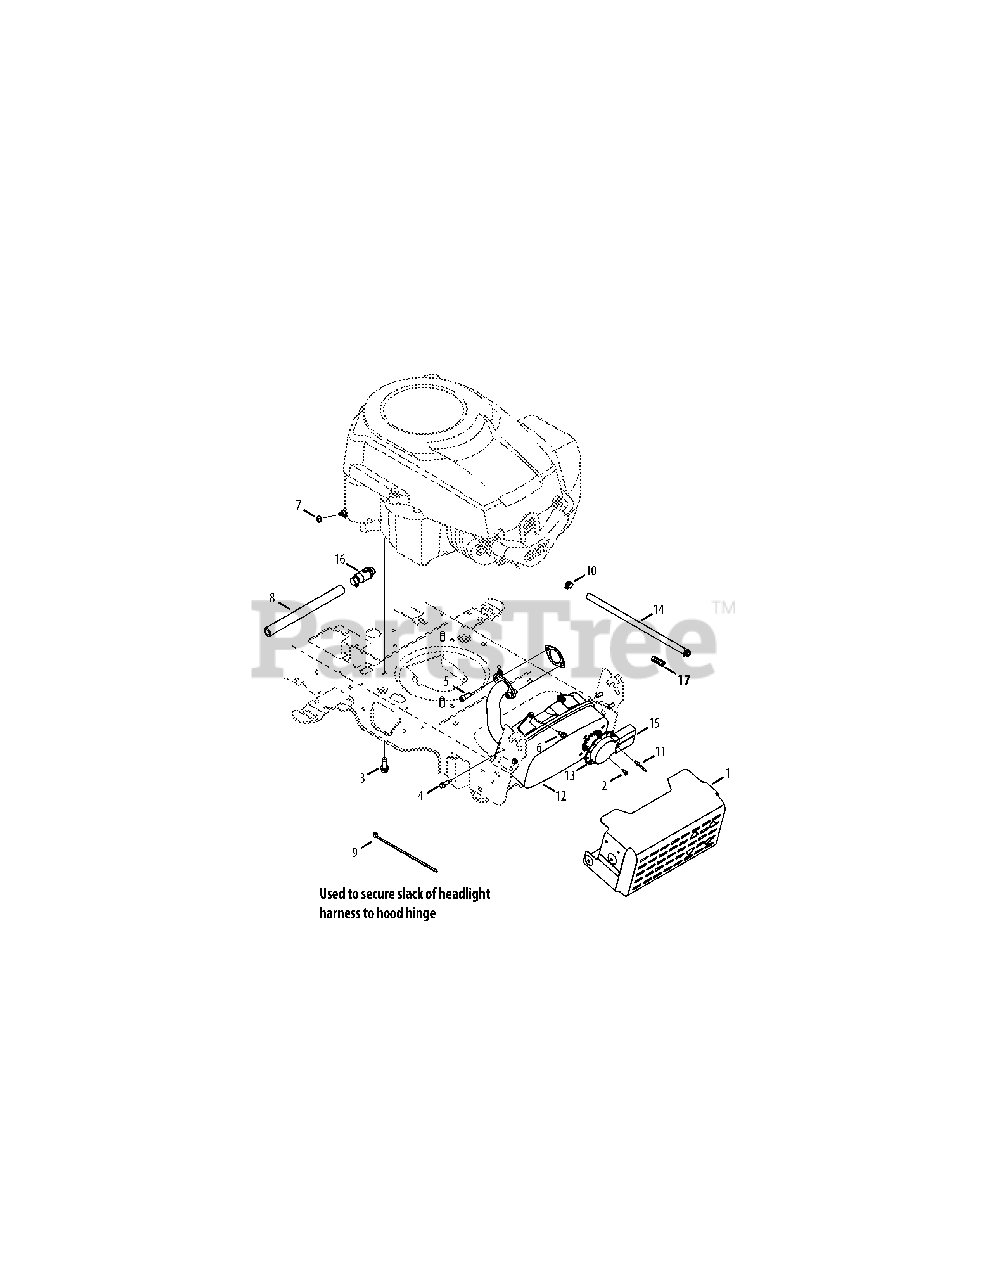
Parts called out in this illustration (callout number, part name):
1	Muffler Shield Assembly
2	Screw, Indented Washer, #8-18:0.500
3	Taptite Screw, 3/8-16:1.000
4	Taptite Screw, 1/4-20:0.500
5	Socket Head Screw, 5/16-18:.750
6	Taptite Screw, 1/4-20 x .625
7	Sems Nut, 1/4-20
8	Extension Hose, Oil Drain
9	Cable Tie, 3/16 x .05 x 7.4
10	Hose Clamp, .490 DIA.
11	Rivet, .188 DIA x .300 L
12	Muffler, EPA
13	Muffler Deflector
15	Long Muffler Deflector, EPA
